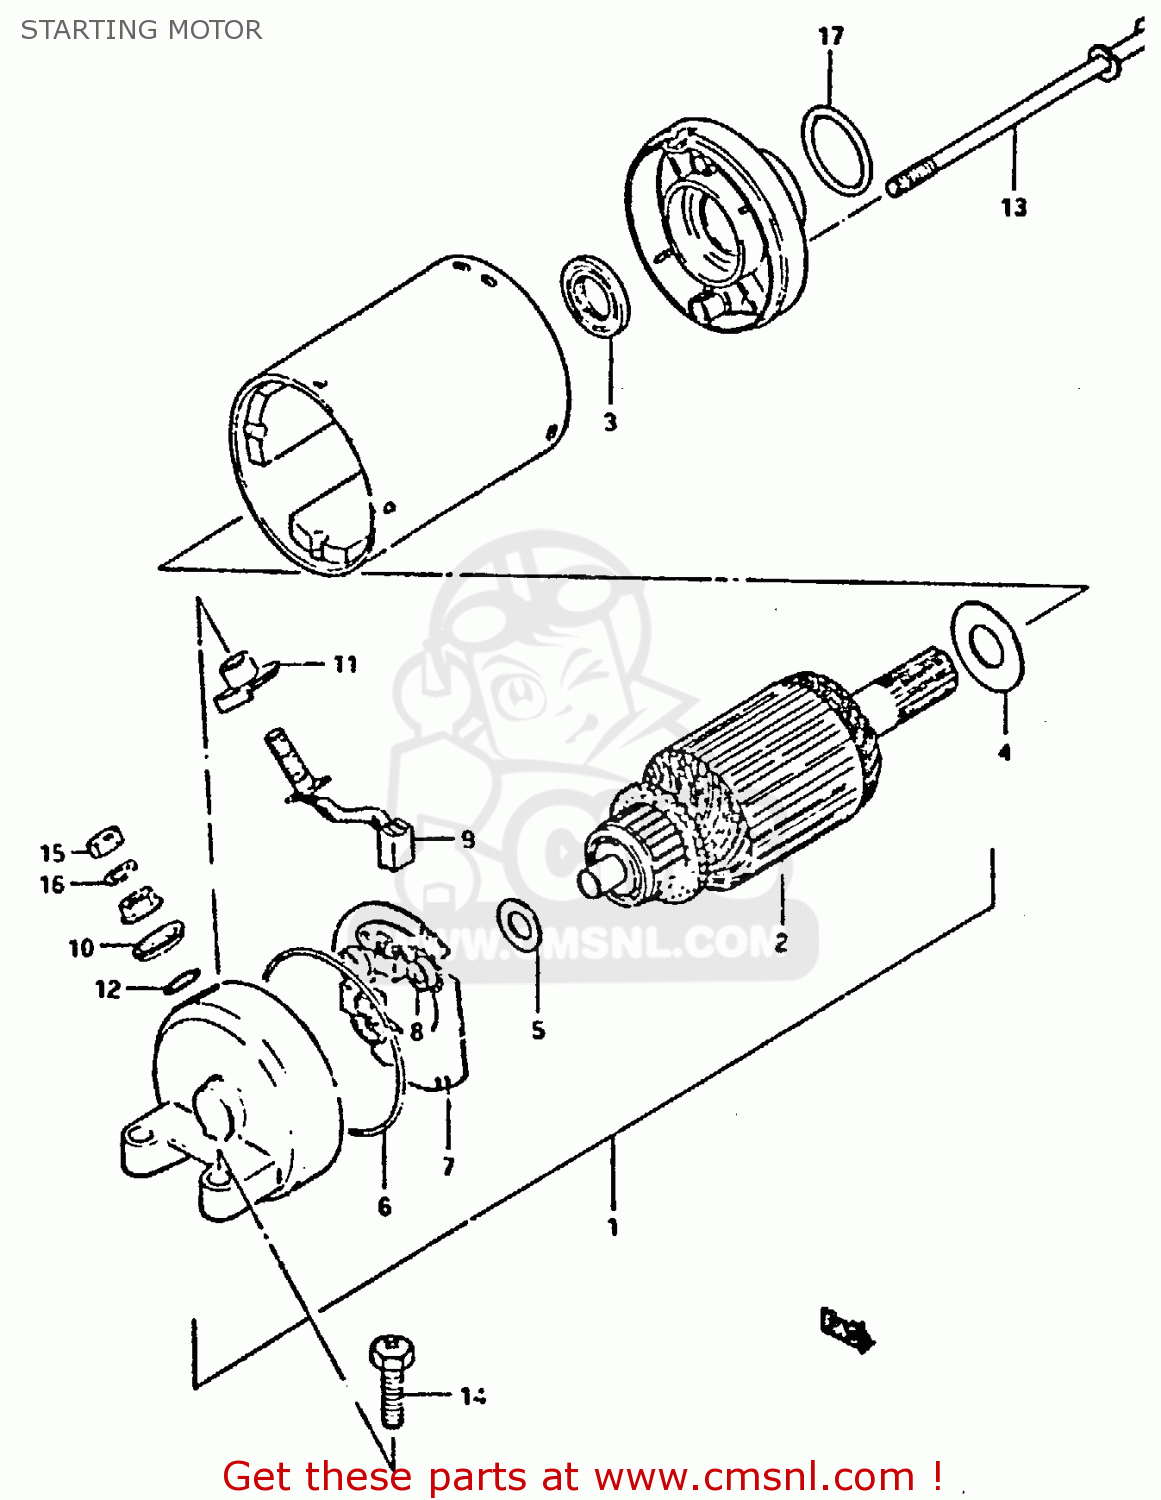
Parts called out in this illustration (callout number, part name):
1	MOTOR ASSEMBLY,STARTING
2	ARMATURE
3	SEAL,OIL
4	RING,SNAP
5	SHIM,ARMATURE
6	O RING
7	HOLDER,BRUSH
8	SPRING
9	BRUSH (+)
10	BUSHING (1)
11	BUSH,NO.2
12	O-RING
13	BOLT,STARTING MOTOR HOUSING
14	SCREW (6X25)
15	NUT 6MM
16	LOCK WASHER
17	O RING(D:3,ID:24.5)
